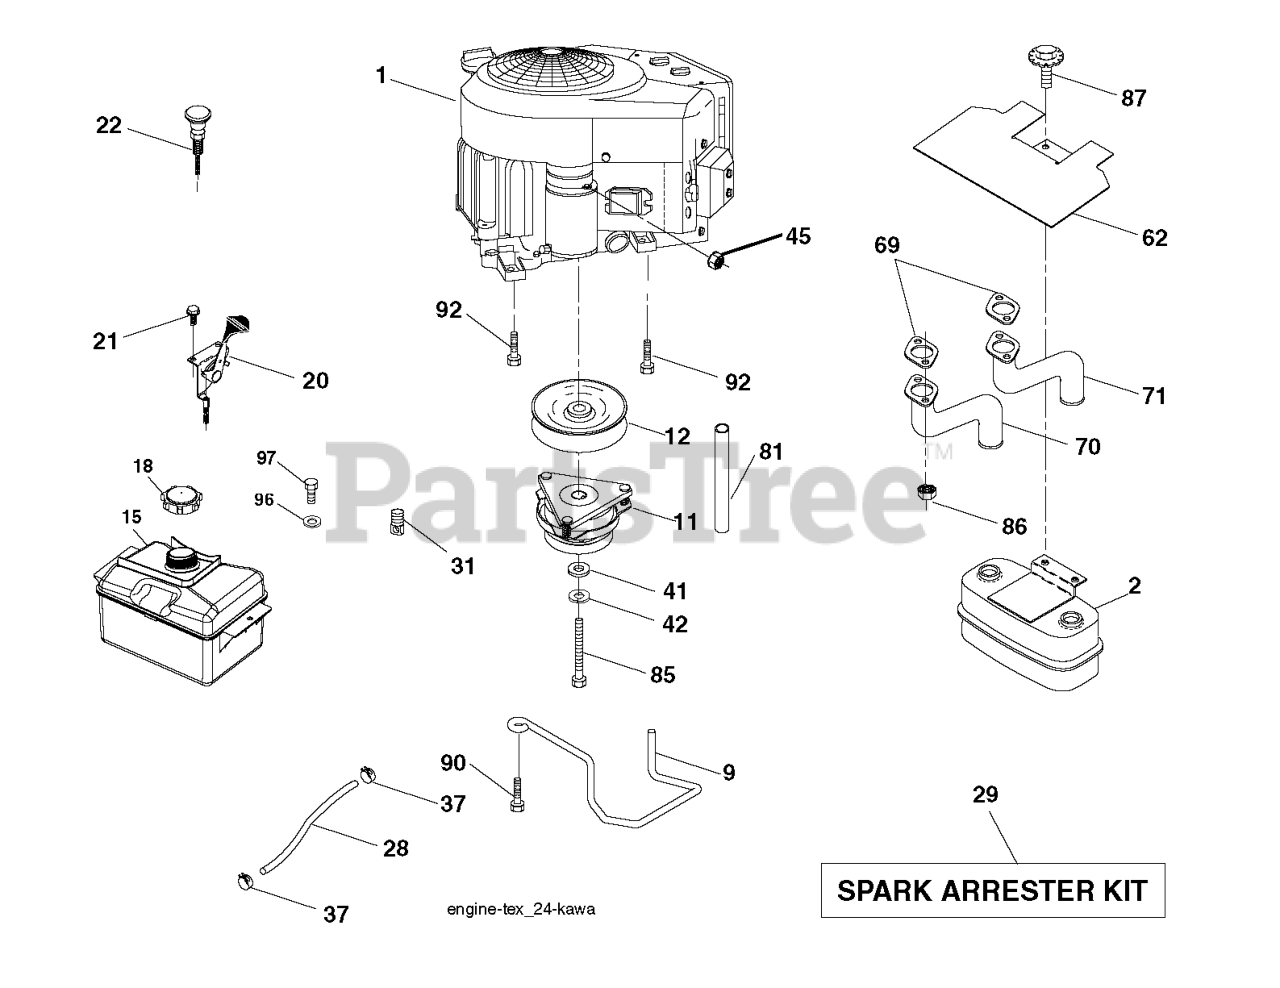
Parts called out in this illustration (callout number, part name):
2	MUFFLER.TWIN.CYL.LOW.TONE
9	KEEPER.BELT.ENGINE.4.2
11	RB.CLUTCH.OGURA.4.4.PD
12	PULLEY.ENGINE.TUFFTORQ
15	RP TANK FUEL FRT 1.5 GAL
18	FUEL CAP
20	THROTTLE CONTROL
21	SCREW
22	CONTROL, CHOKE
28	LINE.FUEL.20
29	KIT.SPARK ARRESTOR 794945 B&S
37	HOSE CLAMP
42	LOCKWASHER
45	NUT
62	RP SHIELD HEAT MUFFLER
69	GASKET.EXHAUST.KAWASAKI.15-1
70	EXHAUST.TUBE.LH.KAWASAKI.
71	EXHAUST.TUBE.RH.KAWASAKI.
81	TUBE, DRAIN OIL ASM.
83	BOLT.5/16-18UNCX3/4 W/SEMS.BLK
86	NUT.HEX.FLANGE.TOPLOCK
87	BOLT.5/16-18UNCX3/4 W/SEMS.BLK
90	SCREW 3/8-16X1
92	SCREW 3/8-16X1
97	SCREW HEXWSHR 1/4-20X3/4
